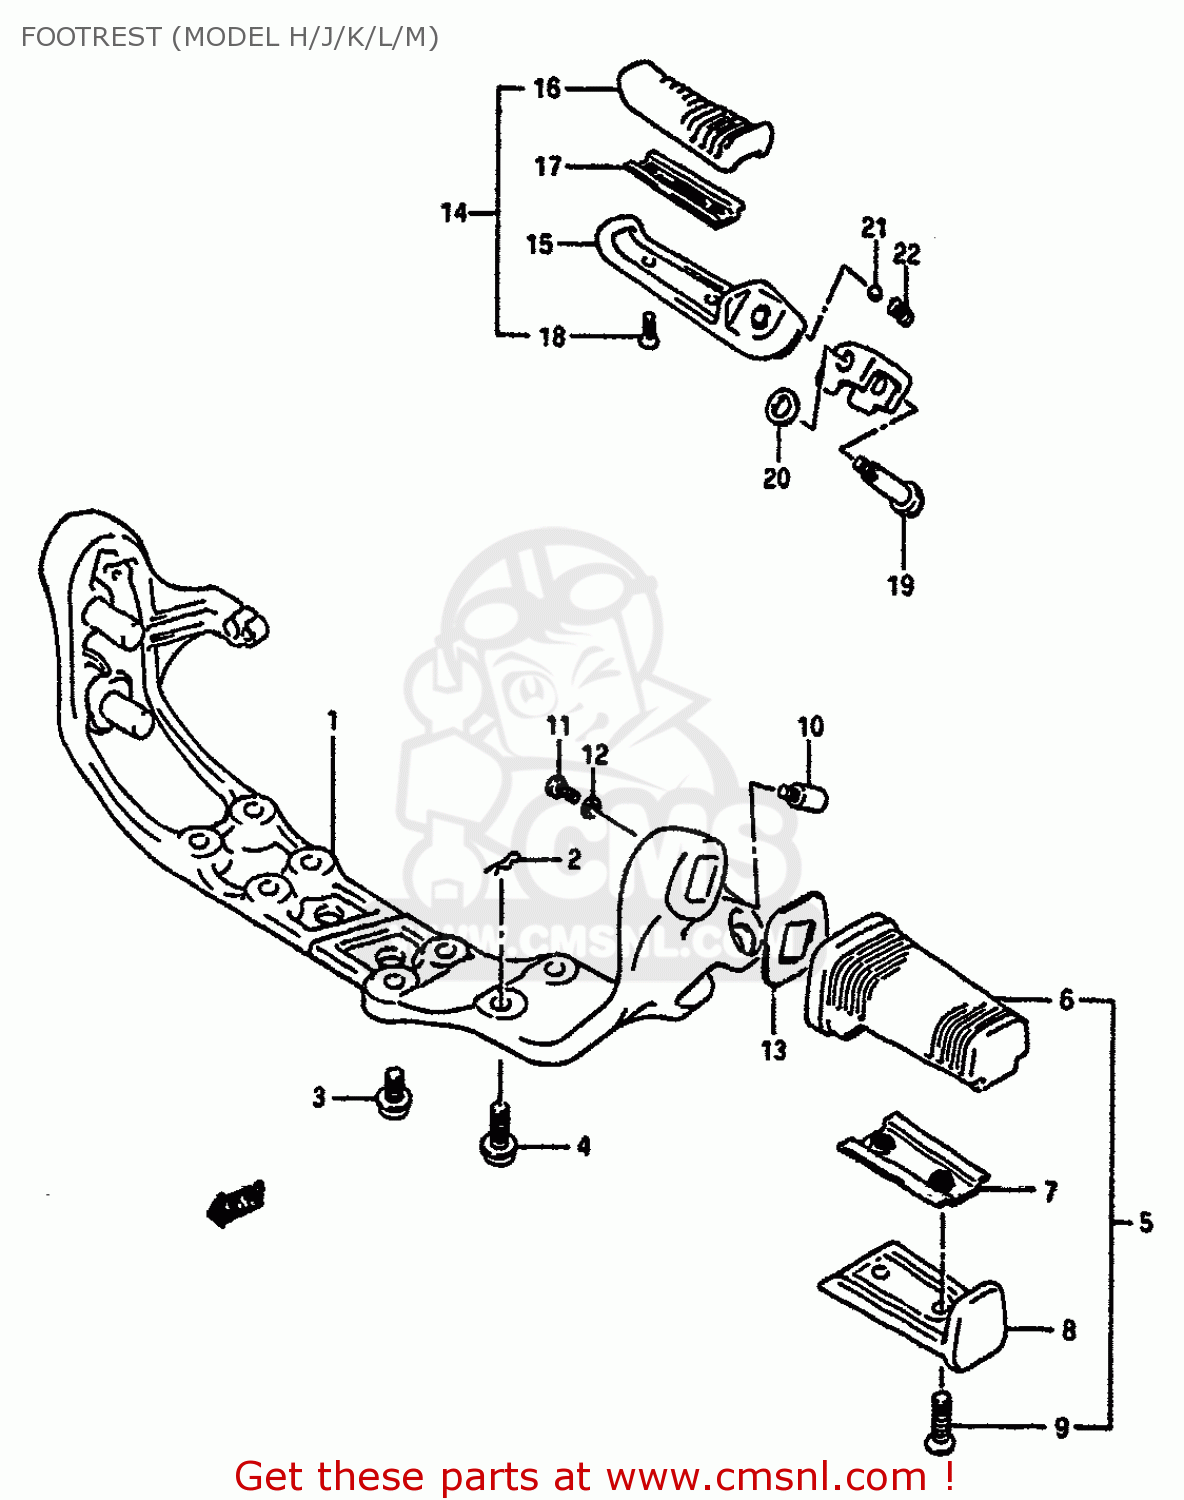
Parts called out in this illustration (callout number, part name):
1	BRACKET COMP,FRONT FOOTREST
2	SNAP
3	BOLT
4	BOLT(8X25)
5	FOOTREST ASSEMBLY,FRONT,LEFT
6	RUBBER,FR FOOTREST
7	PLATE,RUBBER STOPPER
8	COVER,FRONT FOOTREST
9	SCREW
10	BOLT,FRONT FOOTREST
11	BOLT 5X12
12	LOCK WASHER
13	WASHER,FRONT FOOTREST
14	FOOTREST ASSY RH
15	BAR COMP,PILLION FOOTREST
16	RUBBER,PILLION FOOTREST
17	PLATE,RUBBER STOPPER
18	SCREW 5X16
19	BOLT(6X34.5)
20	SHIM
21	BALL
22	SPRING
